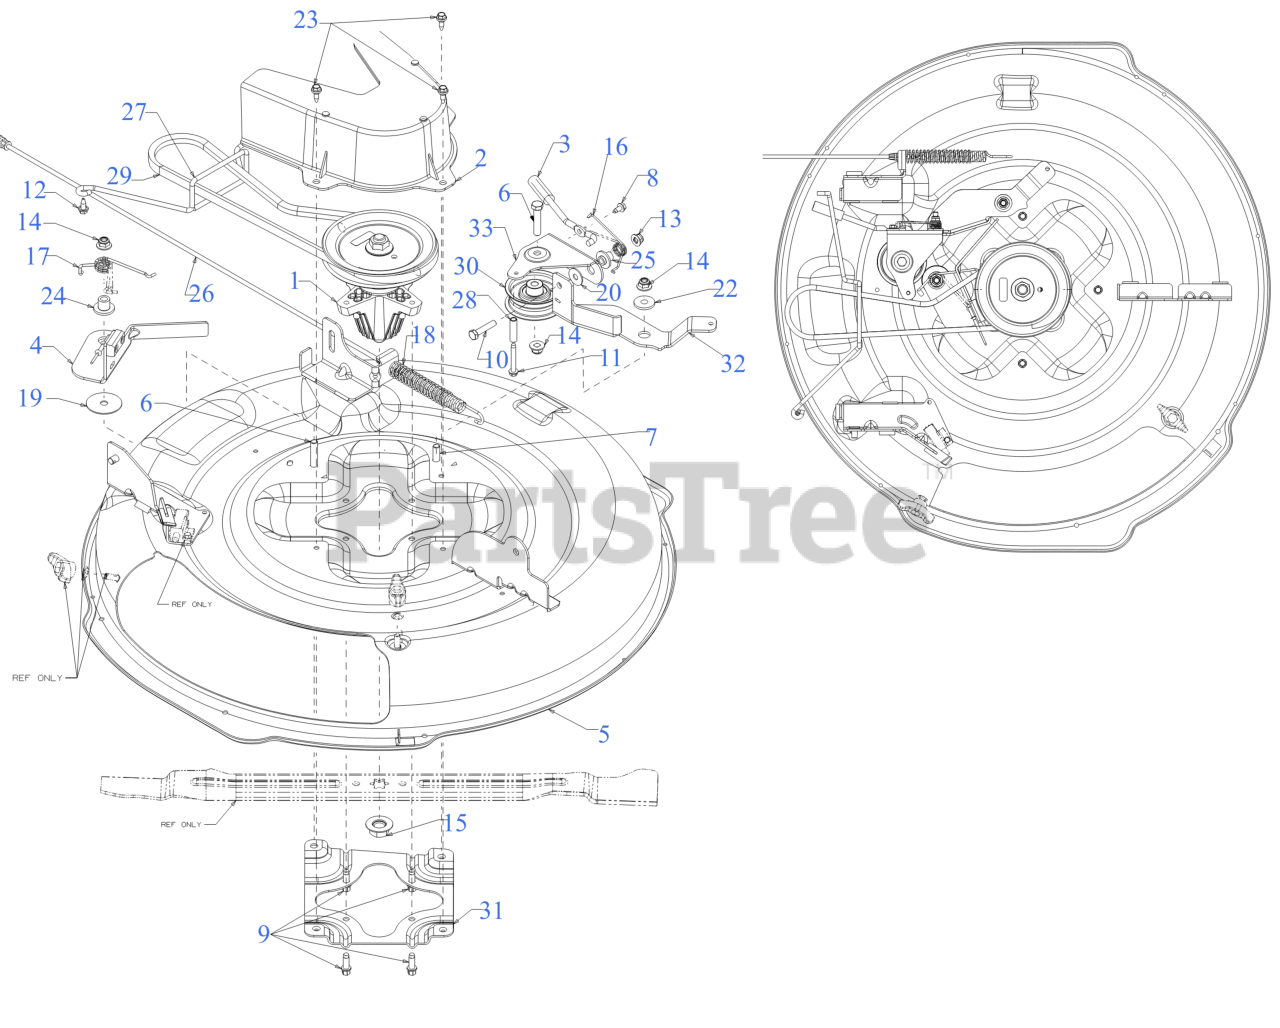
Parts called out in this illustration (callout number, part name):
1	SPINDLE ASSEMBLY
1	Cub Cadet SPINDLE ASSEMBLY
1	Genuine Factory Parts SPINDLE ASSEMBLY
2	DECK BELT COVER ASSEMBLY
3	IDLER GUIDE ROD ASSEMBLY
4	BRAKE PTO BRACKET ASSEMBLY
5	30" DECK SHELL (W/O NOZZLE)
6	HEX SCREW 3/8-16 x 1.75 GR5
7	SCREW 3/8-16 x 1 GR5
8	SCREW 1/4-20 X.500
9	SCREW 5/16-18 x .875
10	SCREW 5/16-18 x 1.5 LG
11	SCREW 1/4-20 x 1.750
12	SCREW 1/4-20X.625
13	FLANGE LOCK NUT 5/16-18
15	FLANGE NUT 5/8-18
16	TORSION SPRING PTO
17	TORSION SPRING BRAKE
18	SPRING
19	HUB CAP WASHER .406 x 1.92 x .060
20	FLAT WASHER 344X1.00
22	SHOULDER SPACER
23	SHOULDER SCREW
24	DOUBLE SHOULDER SPACER
25	DOUBLE SHOULDER SPACER
26	PTO CABLE
27	DECK BELT KEEPER
28	SPACER:.260 x .372 x 1.420
29	V-BELT A SEC 43.5
30	FLAT IDLER PULLEY 2.75 OD
32	IDLER BRACKET FLOATING LOWER
